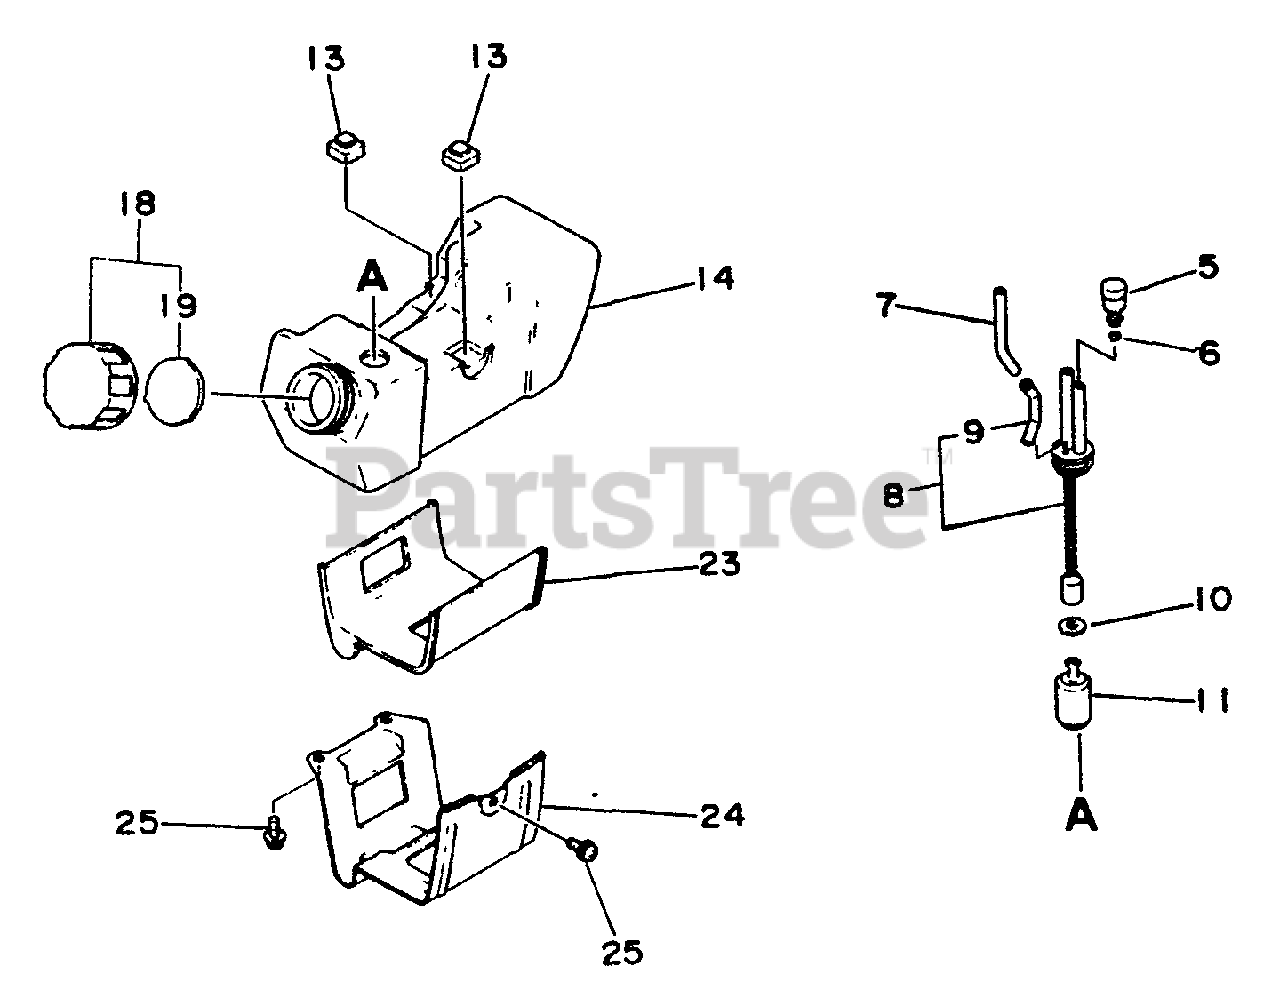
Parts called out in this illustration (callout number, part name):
5	VENT, FUEL TANK
6	CLIP - 5.5
7	PIPE - 3X6X45 -- CLEAR
8	FUEL SYSTEM KIT
9	CONNECTOR, PIPE
10	WASHER - 5
11	FILTER, FUEL
13	CUSHION
14	TANK, FUEL
18	CAP ASSY
19	GASKET, CAP
23	CUSHION
24	GUARD, FUEL TANK
25	SCREW - 5X10
